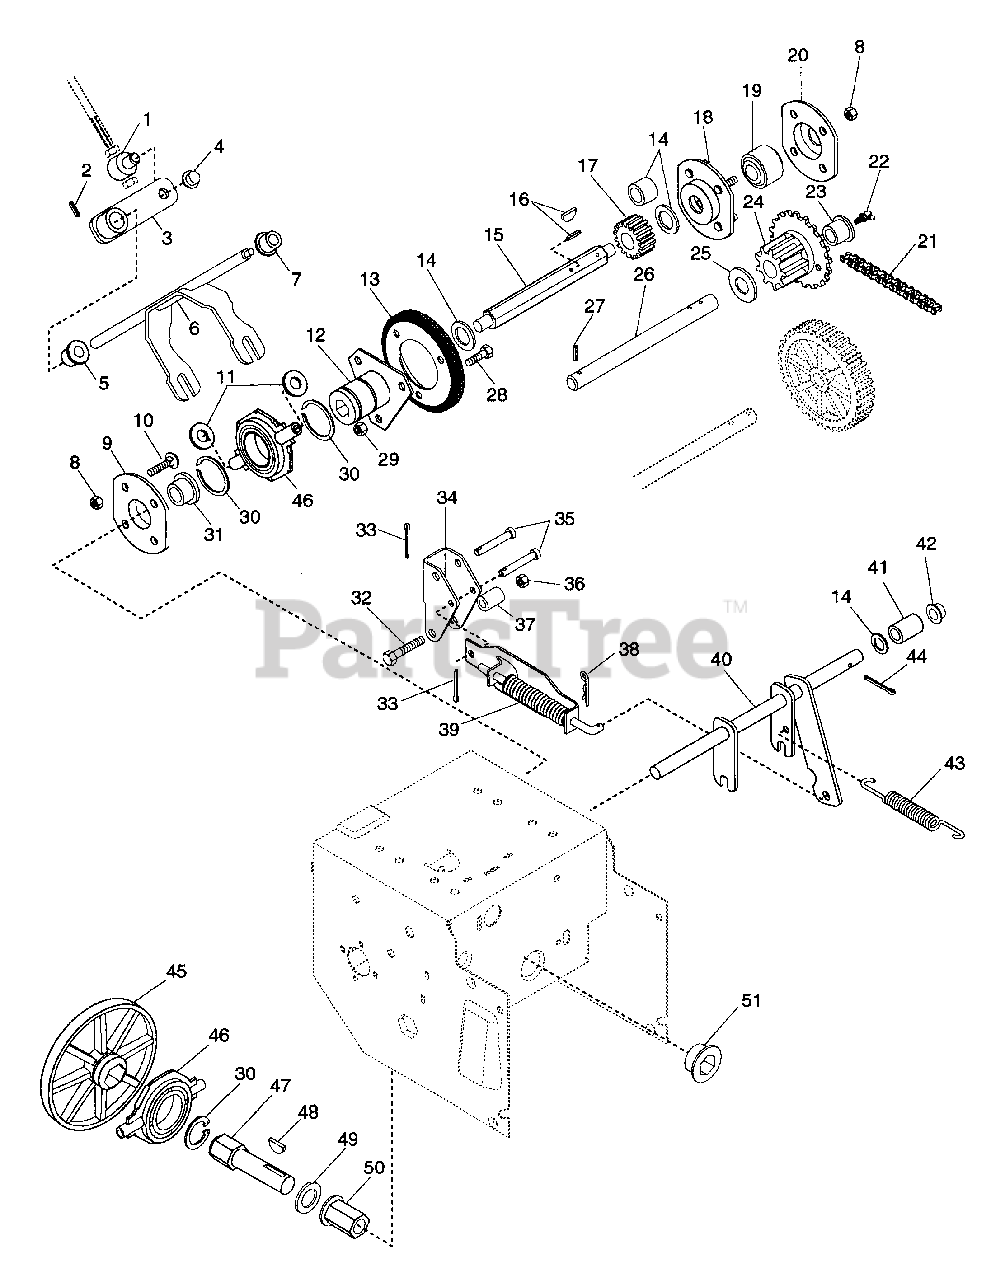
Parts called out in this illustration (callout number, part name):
2	PIN-ROLL .156X.88
3	ARM-SPEED CHANGE
4	CAP, 3/8 ROD YWZC
5	BSHG-FLG.500X.625X.312X.750NY
6	FORK-SPEED
7	BSHG-FLG .325X.444X.440X.560
8	NUT-LK DUAL FACE 10-24 PL
9	BUSHING FLANGE
10	BLT-RDHDSQNK 10-24X.38 PL
11	WSHR-FL-STL .505X1.000X.062
12	FRICTION WHEEL HUB
13	FRICTION DISC
14	WSHR-FL-STL .531X1.062X.095 PL
14	SPACER .513X.748X.620
15	HEX SHAFT
16	PIN-ROLL .125X.88
16	KEY-WDRF .125X.625X.250 SAE5
17	PINION
17	9 TOOTH SPROCKET
18	BEARING FLANGE
19	BRG-BALL .500X1.38X.437
20	BEARING FLANGE
21	CHAIN-ROLLER #41X26 PITCHES
22	HYDRAULIC DRIVE FITTING
23	BSHG-FLG .625X.750X.500X.875BR
24	SPROCKET ASSY
25	WSHR-FL-STL .630X1.005X.062 PL
26	SHAFT-PINION
27	PIN-ROLL .125X1.00
28	BLT-HEX .25-20X.50 PL GR2
29	NUT-LK-CTR .250-20 PL
30	RG-RTNG-EXT 1.250X.050
31	BSHG-FLG .500X.750X.625X.937
32	BLT-HEX .31-18X1.50 PL GR2
33	PIN COTR .09X.50 PL
34	BRACKET
35	PIN, CLEVIS .243/.248X1.50 YWZ
36	NUT-LK .312-18 GR A PL
37	SPACER -SPLIT .340X.490X1.02
38	PIN-HAIR INT .08X.18X1.18
39	TRACTION CLUTCH ASSY
40	CLUTCH FORK
41	SPACER .504X.748X.321
42	CAP, .50 ROD YWZC
43	SG-TENS .063X.44X1.56
44	PIN-COTR .12X1.0 PL
45	FRICTION PLATE
46	BEARING ASSEMBLY
47	HEX SHAFT
48	KEY-WDRF .188X.75X.313 SAE 9
49	WSHR, THRUST .625X1.125X.063
50	BSHG-FLG .625X.875X1.750X1.188
51	BSHG-FLG .875X1.25X.75X1.50HX
